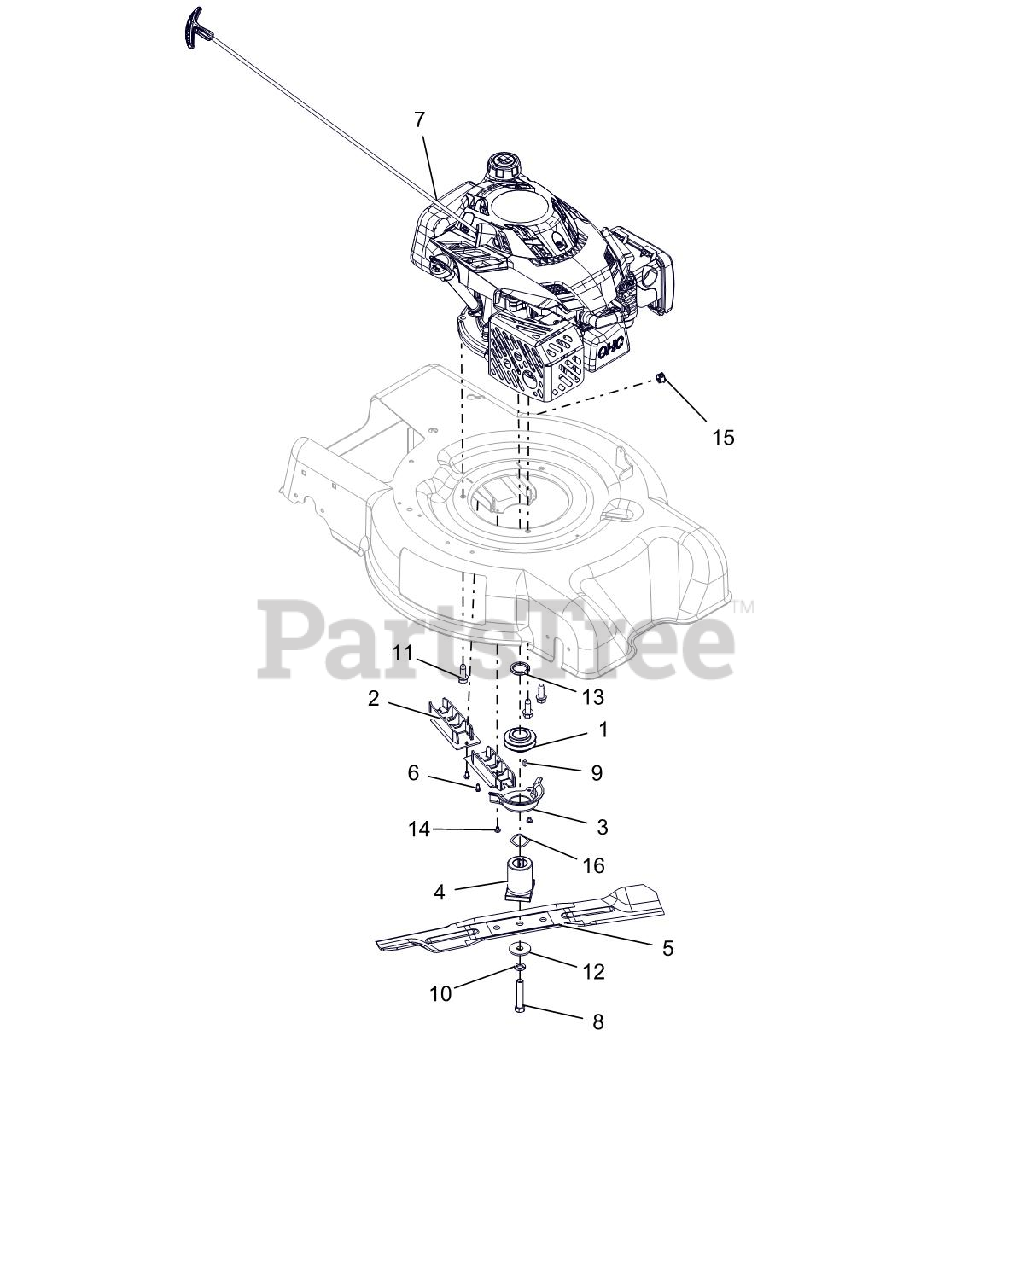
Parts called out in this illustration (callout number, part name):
1	PULLEY, GROUND DRIVE, LM
2	GUIDE, BELT INNER
3	GUIDE, BELT CRANK
4	ADAPTER, BLADE
5	BLADE, MOWER 21" HIGH LIFT
6	SCR-TAP 10-24X.375 PRE-COAT 80
7	ENGINE, SUBARU 175CC VERT. ES
8	@BLT-HEX .4375-20X2.25 GR8 YWZ
9	KEY-SQ .188X.188X.375
10	@WSHR-LK .44X.109 REG YWZC
11	@SCR-TAP .38-16X1.00 HWH TR YZ
12	WSHR-FL-STL .4375X1.50X.125 YZ
13	SPCR, 1.00 X 1.375 X .179
14	SCR-TAP 10-24X.25 CRSLPH TR YZ
15	PLUG, DOME-BLACK, .625 DIA
16	WASHER - WAVE 1.09X1.37X.016
